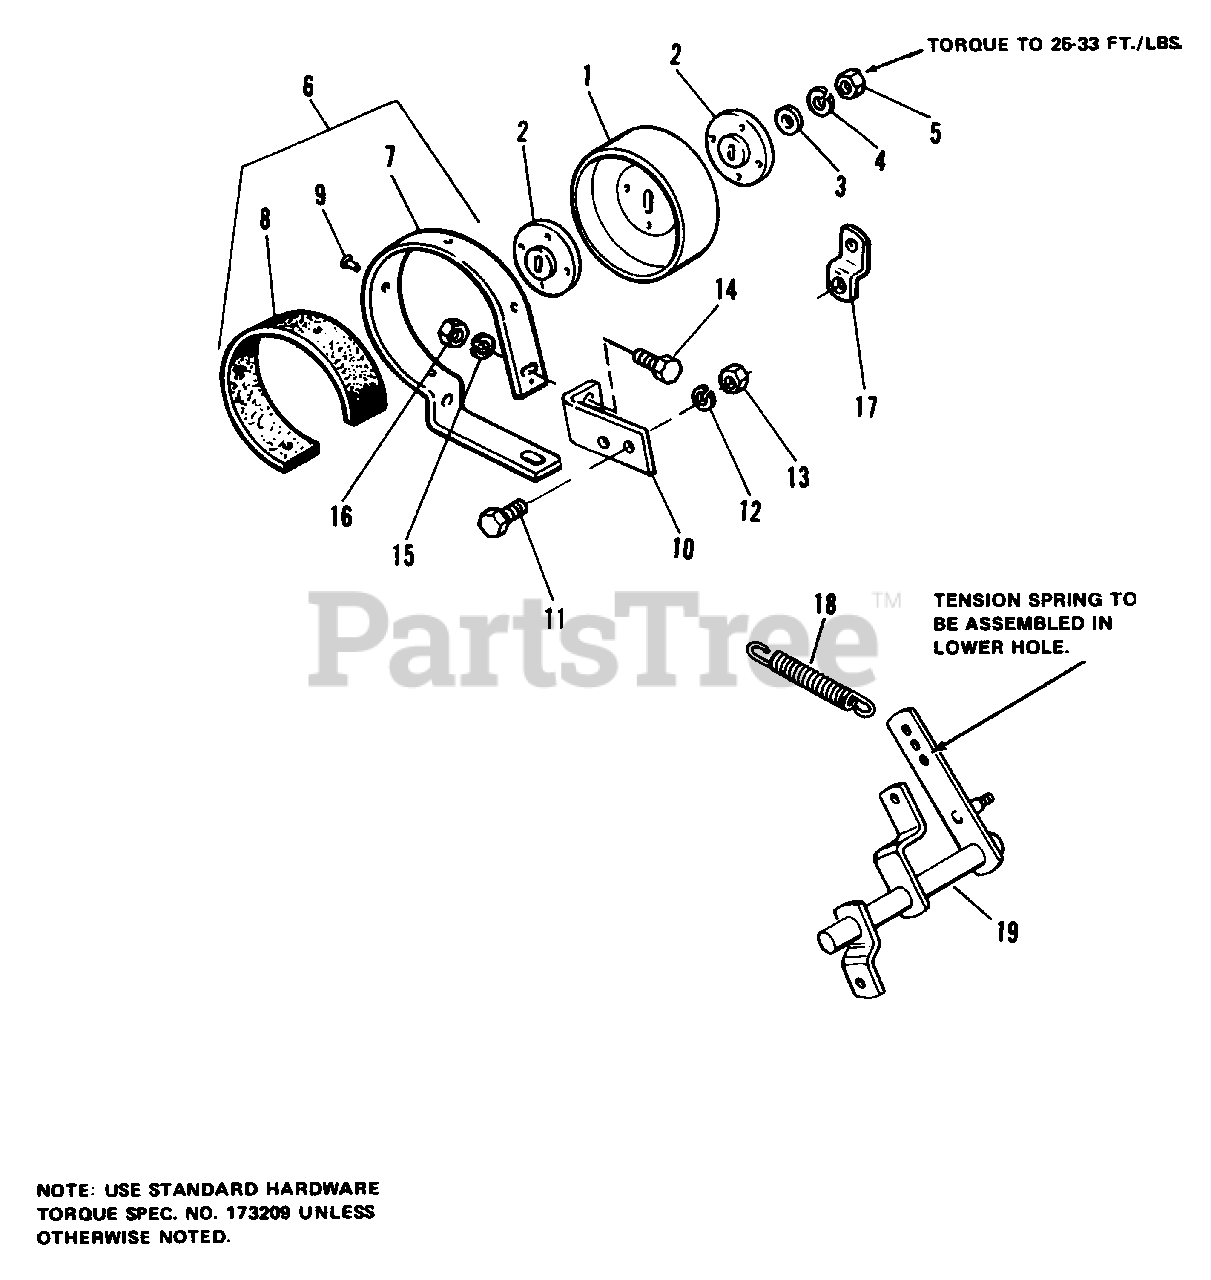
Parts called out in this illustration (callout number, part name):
1	DRUM, Brake
2	WASHER, Special
3	WASHER, 3/8
4	LOCKWASHER, 7/16
5	NUT, Hex, Full, 7/16-14
6	BAND ASSY, Brake
7	BAND, Brake
8	LINING, Brake
9	RIVET, Tubular
10	BRACKET, Brake Band
11	CAPSCREW, Hex Hd., 3/8-16 x 1
12	LOCKWASHER, 3/8
13	NUT, Hex, Full, 3/8-16
14	CAPSCREW, Hex Hd., 1/4-20 x 3/4
15	LOCKWASHER, 1/4
16	NUT, Hex, Full, 1/4-20
17	CLIP, Spring
19	LEVER ASSY, Pivot
